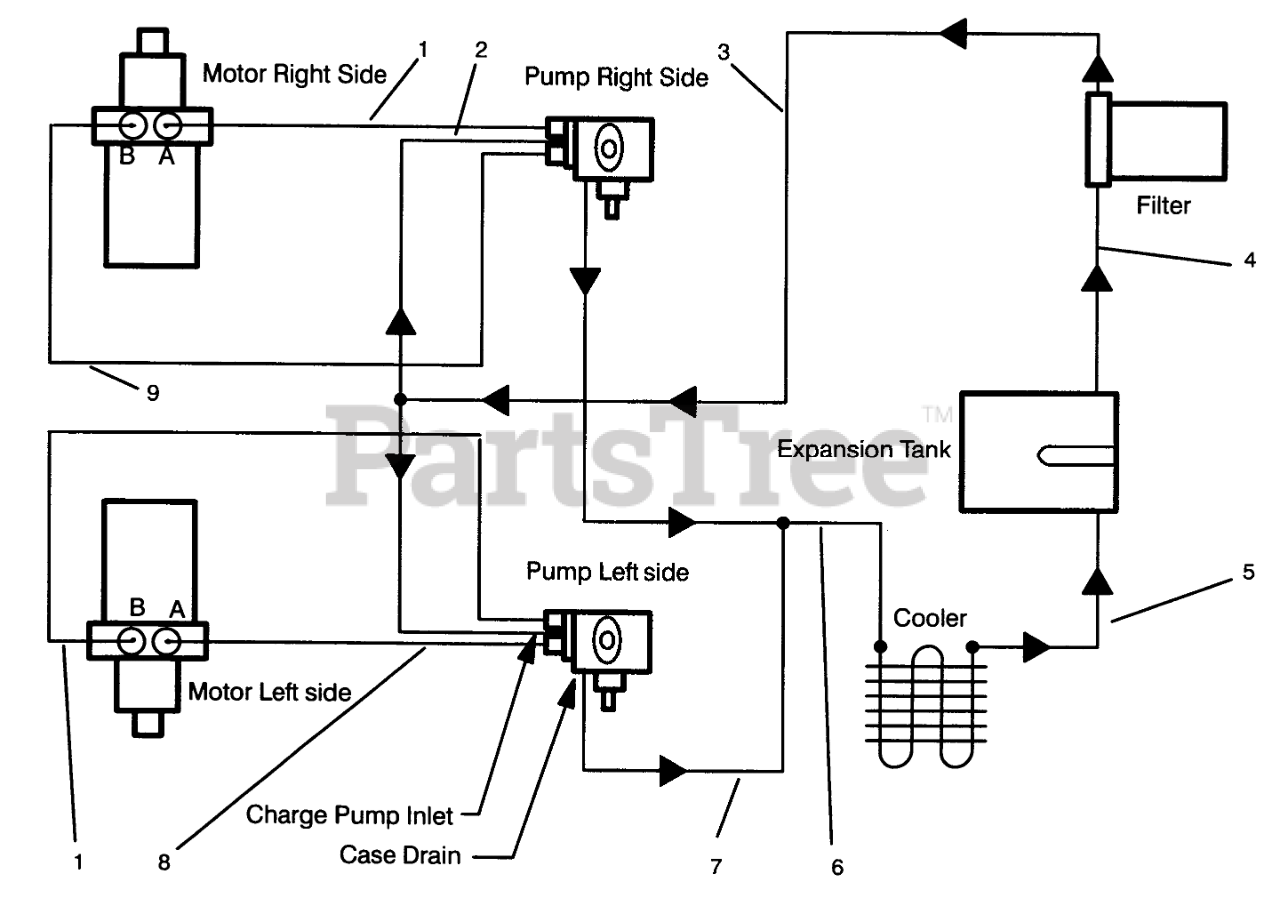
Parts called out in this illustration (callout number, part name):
1	HYDRAULIC HOSE ASM
2	HYD HOSE ASM
3	HYDRAULIC HOSE ASM
4	HYD HOSE ASM
5	HYDRAULIC HOSE ASM
6	HYDRAULIC HOSE ASM
7	HYD HOSE ASM
8	HYDRAULIC HOSE ASM
9	HYDRAULIC HOSE ASM
